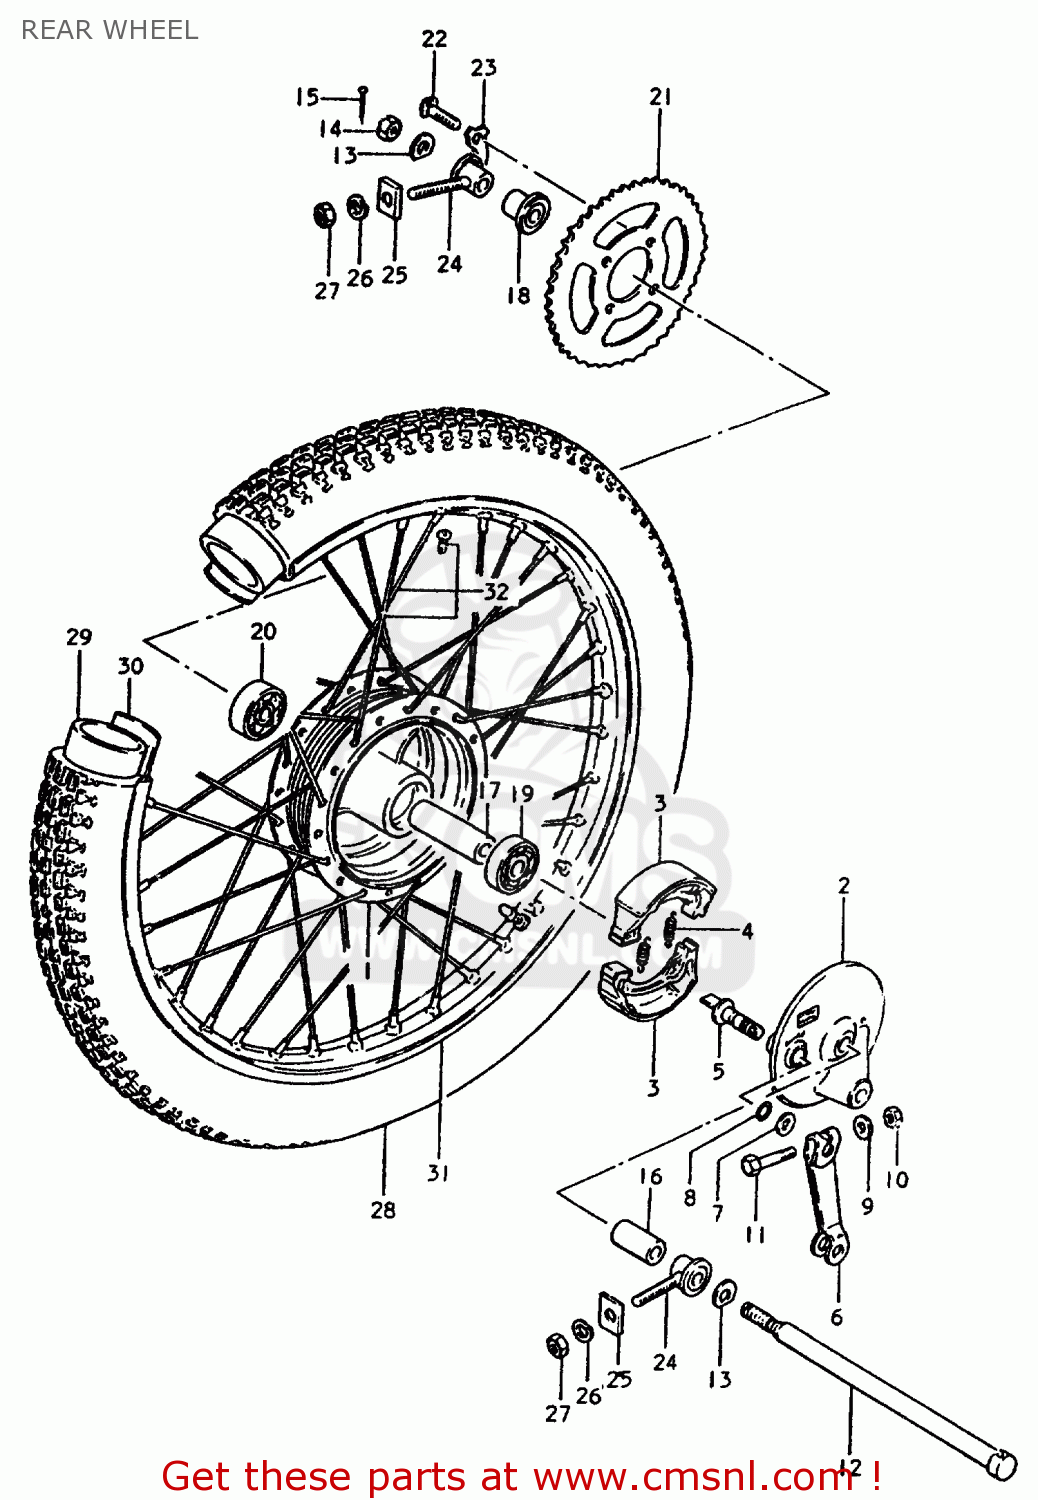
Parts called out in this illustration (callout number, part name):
1	DRUM, REAR HUB
2	PANEL,REAR BRAKE ANCHOR
3	SHOE,BRAKE (MCA)
4	SPRING(L:34)
5	CAM,FRONT BRAKE
6	LEVER,RR BRAKE CAM
7	WASHER (14.5X22X1.6)
8	O-RING (D:2.4 ID:13.8)
9	WASHER
10	NUT
11	BOLT(6X33)
12	AXLE,RR
13	WASHER,RR AXLE
14	NUT 12MM
15	COTTER PIN
16	SPACER, AXLE RH
17	SPACER(12.6X19X91)
18	SPACER, REAR AXLE LH
19	BEARING
20	BEARING
21	SPROCKET, REAR (NT:47)
22	BOLT(8X25)
23	WASHER
24	ADJUSTER, CHAIN
25	ADJUSTER,CHAIN
26	LOCK WASHER
27	NUT
28	TIRE
29	TUBE,INNER
30	PROTECTOR,INNER TUBE
31	RIM, WHEEL
32	SPOKE SET,RR
